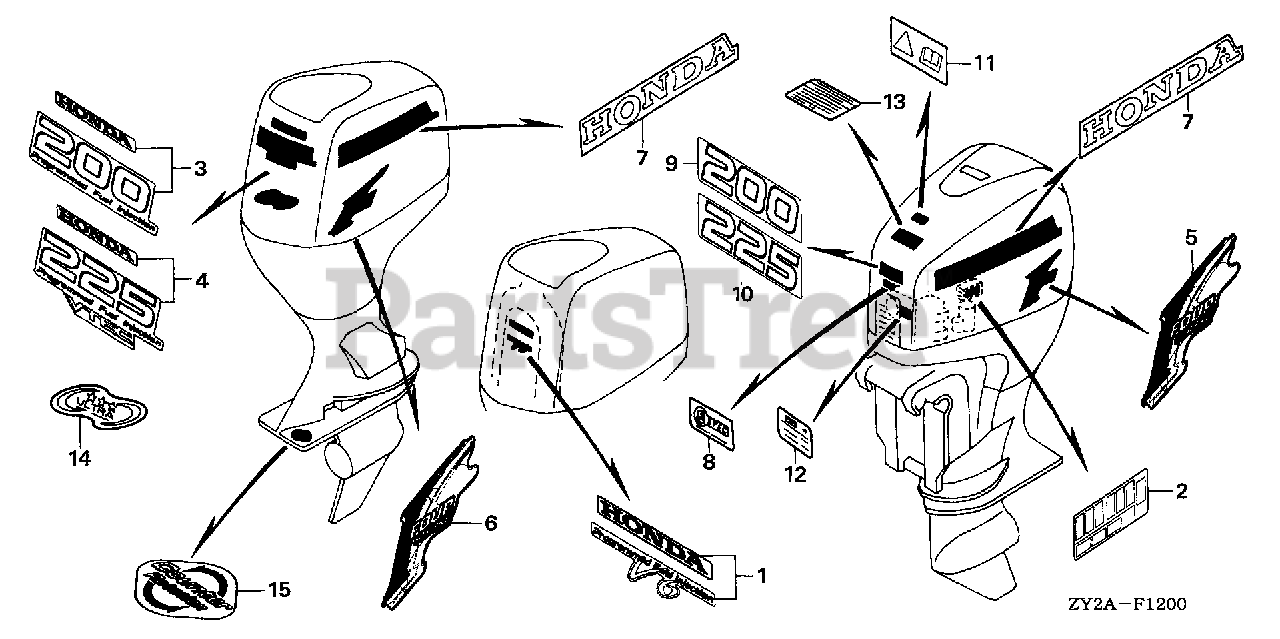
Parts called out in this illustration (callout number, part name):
1	MARK, EMBLEM
2	LABEL, FUSE
4	MARK, RR. (BF225)
5	MARK, SIDE (L. SIDE)
6	MARK, SIDE
7	MARK, SIDE STRIPE (HONDA)
8	MARK (E-SPEC)
10	MARK, FR. EMBLEM (BF225)
12	LABEL, CAUTION OIL (ENGLISH)
13	LABEL, OPERATOR CAUTION (ENGLISH)
13	LABEL, WARNING OPERATOR
